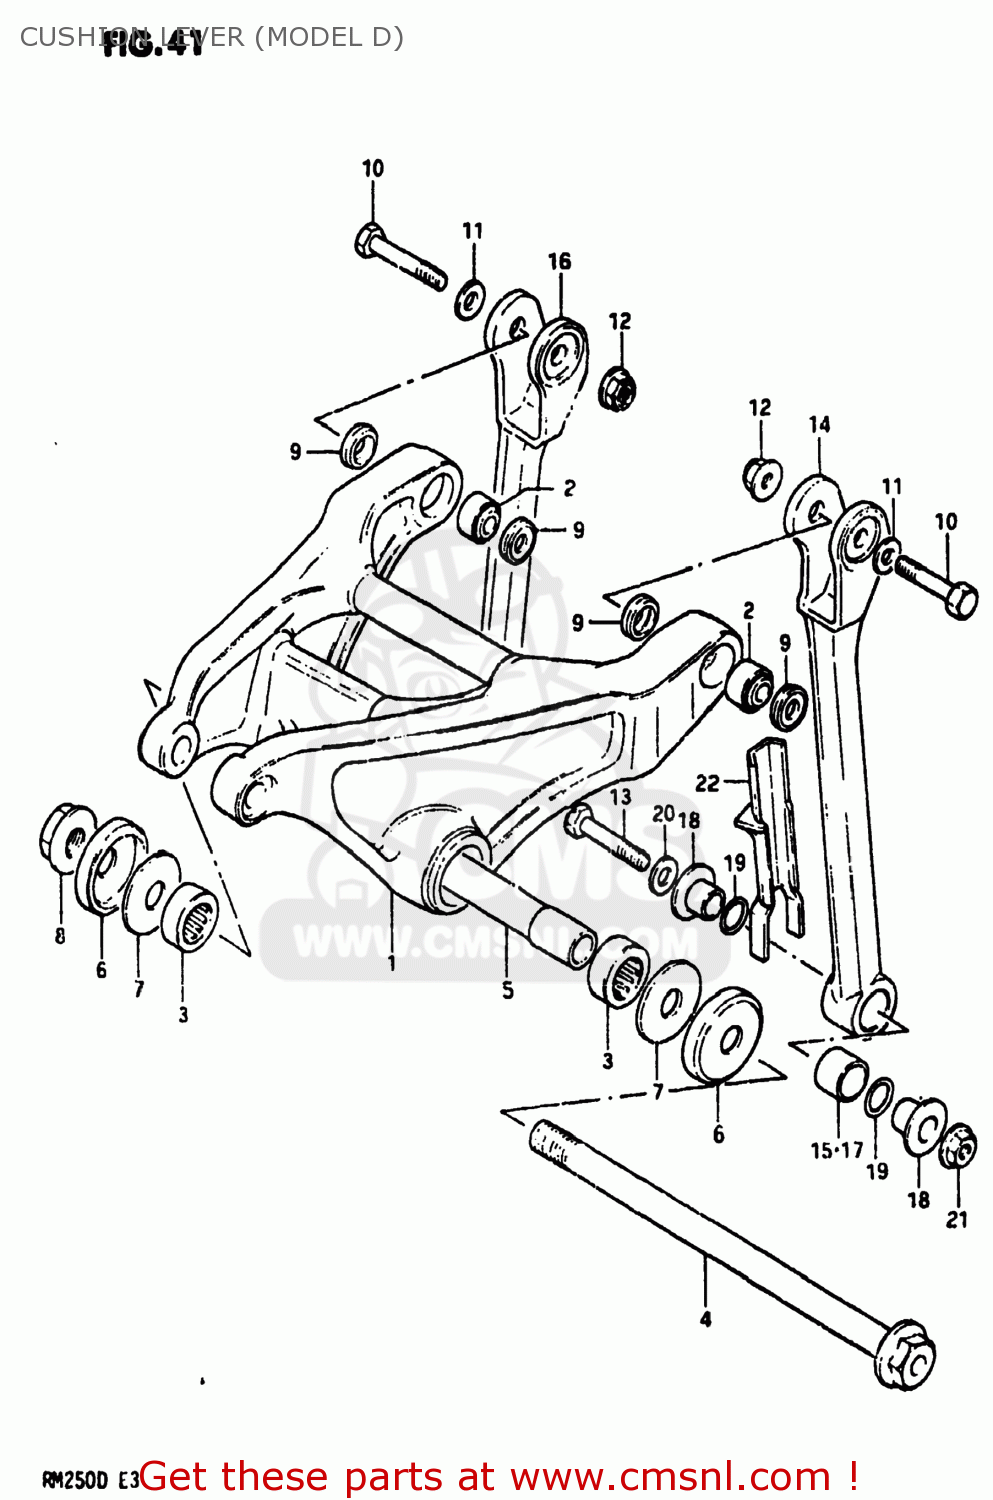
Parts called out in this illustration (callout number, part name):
1	LEVER SET,REAR CUSHION
2	BEARING(8X18X11)
3	BEARING(17X26X20)
4	SHAFT,REAR CUSHION LEVER
5	SPACER,REAR CUSHION LEVER
6	DUST SEAL
7	WASHER(12X35X2)
8	NUT 12MM
9	DUST SEAL,RR CUSHION LOD UPR
10	BOLT,REAR CUSHION LEVER
11	WASHER
12	NUT
13	BOLT,REAR CUSHION LEVER
14	LEVER SET,REAR CUSHION
15	BUSHING
16	LEVER SET,REAR CUSHION
17	BUSHING
18	SPACER,RR CUSHION ROD LWR
19	DUST SEAL,REAR CUSHION
20	WASHER
21	NUT
22	PROTECTOR,REAR CUSHION R
